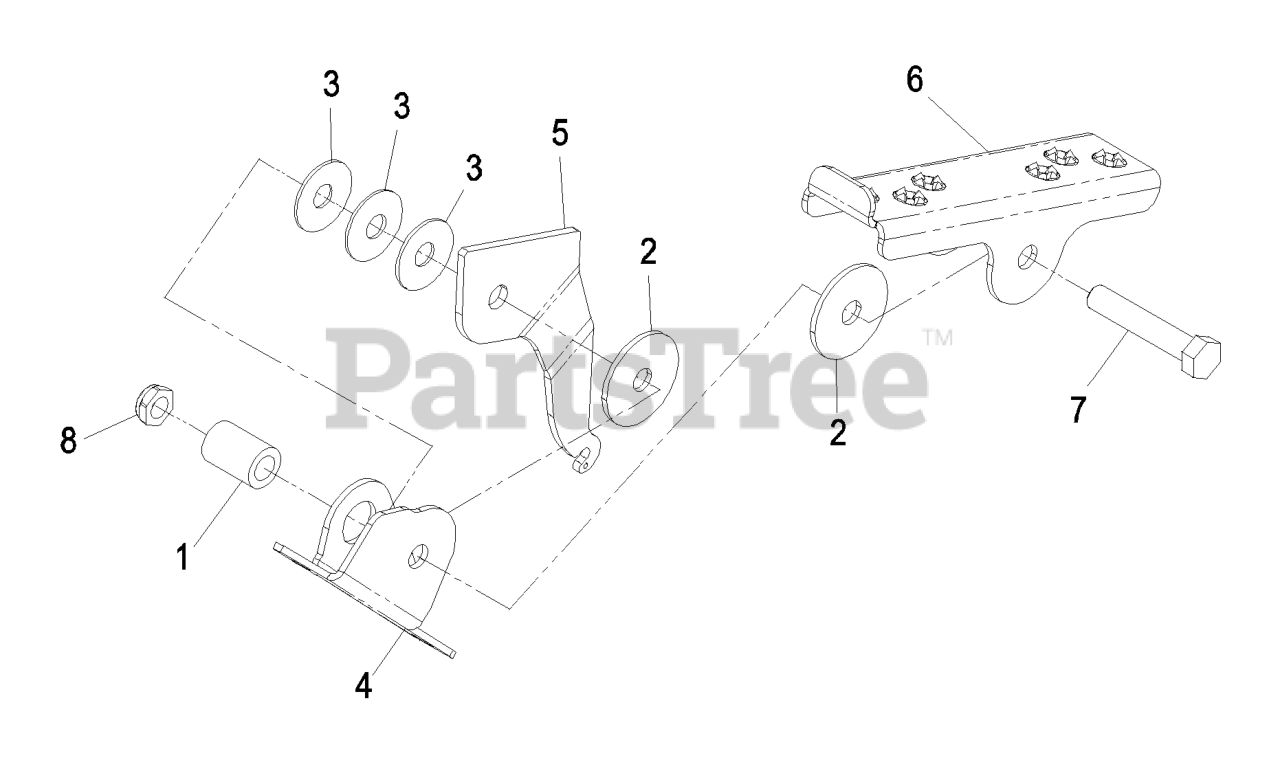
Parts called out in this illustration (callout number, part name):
1	SPACER-ROLLER
2	DISC-FRICTION
3	WASHER-DISC, SPRING
4	BRACKET,PEDAL PIVOT
5	Bracket, Pedal Link
6	Channel, Pedal Link
7	SCREW-HH
8	NUT-HEX
